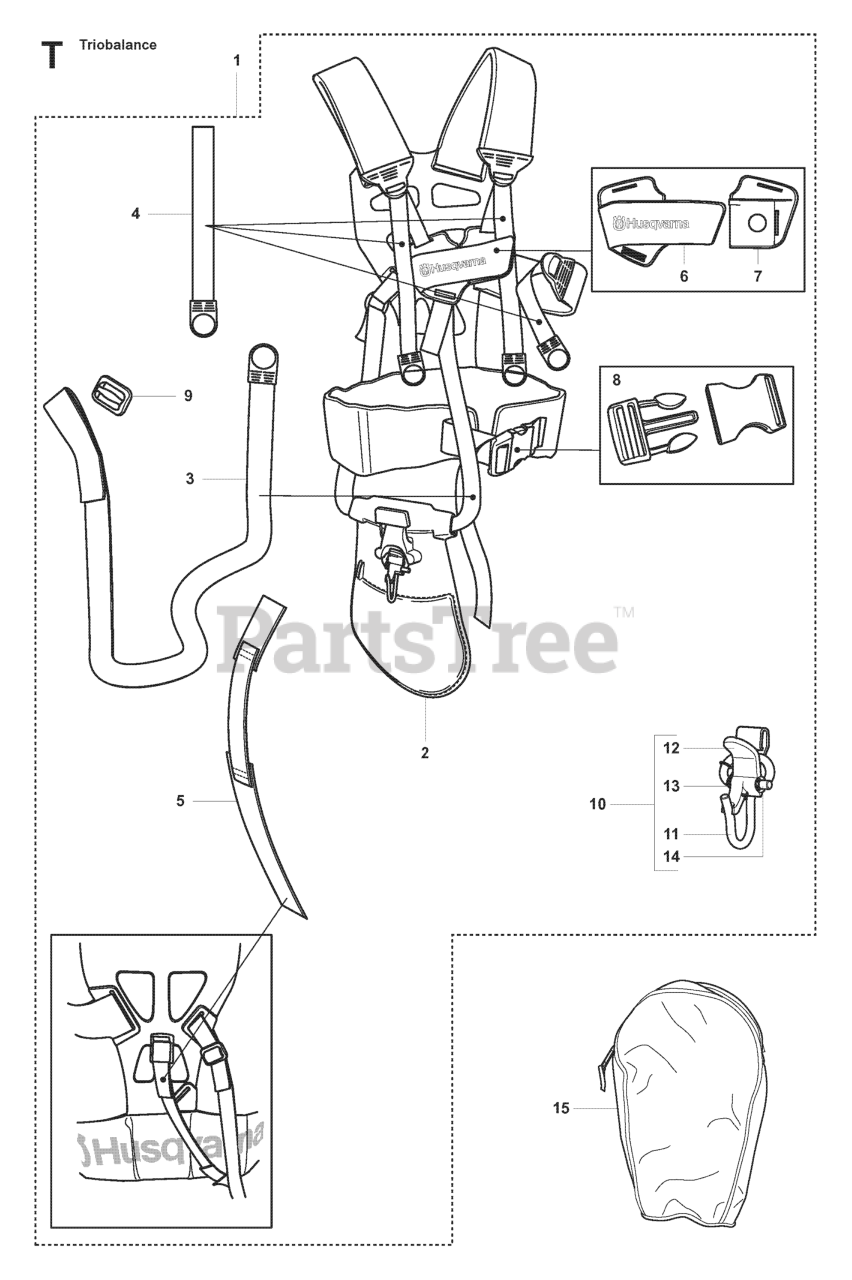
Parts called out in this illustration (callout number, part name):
1	RP HARNESS TRIO BALANCE
6	FRONT PIECE
7	FRONT PIECE
9	RP CLIP
11	HOOK
12	CATCH *
13	SPRING
15	TOOL BAG
